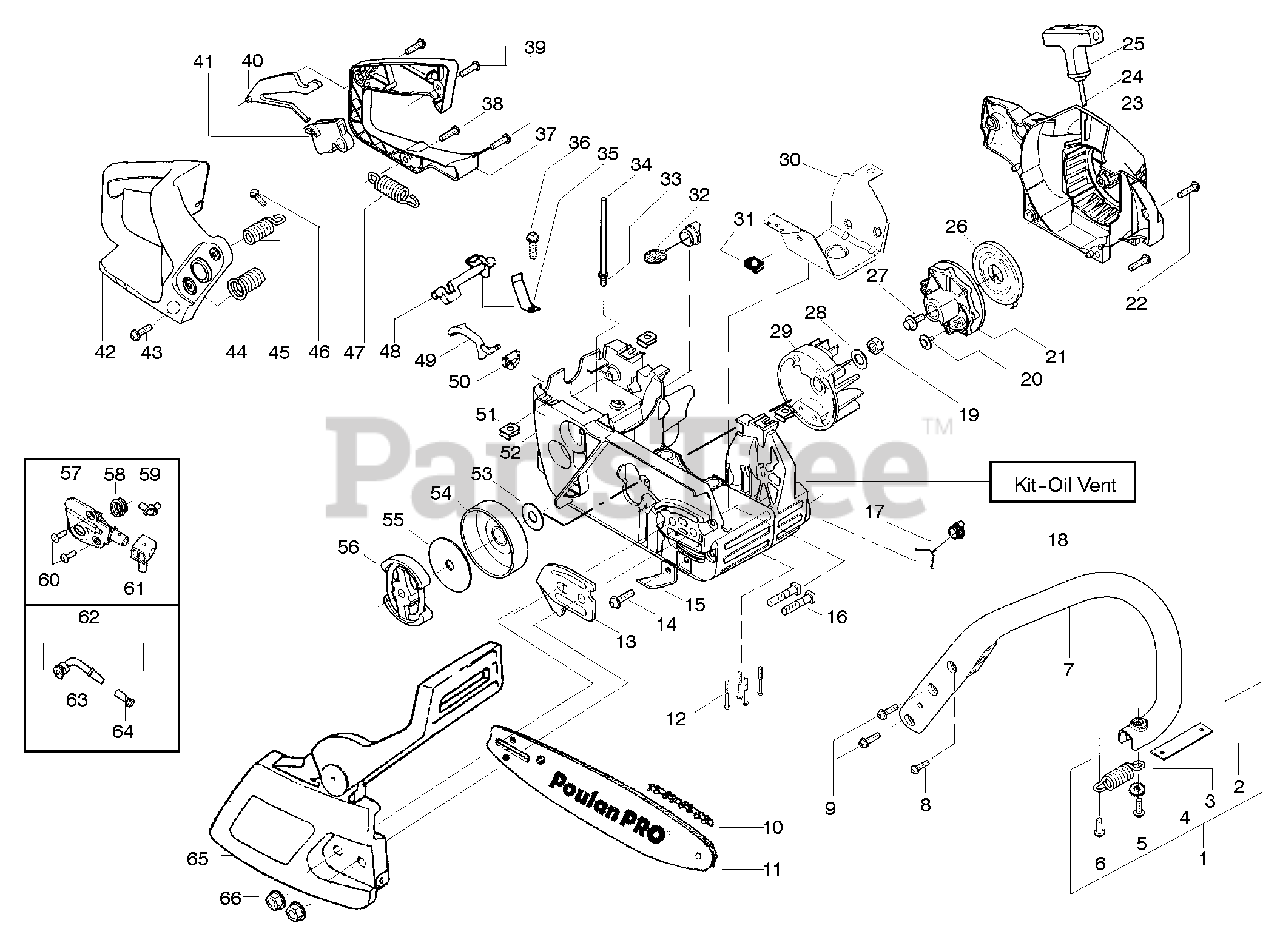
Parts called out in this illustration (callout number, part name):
1	Assy.-Isolator
2	Limiter Strap
3	Spring-Isolator
4	Washer
7	Front Handle
10	Chain -16"
11	Bar - 16"
13	Plate-Bar Mount.
15	Chain Catcher
16	Bolt-Bar
17	Assy-Oil Cap
18	Kit-Oil Vent
19	Nut-Flywheel
21	Starter Pulley
23	Housing-Fan
24	Kit - Rope
25	Handle-Starter
26	Spring-Recoil
28	Washer-Flywheel
29	Assy-Flywheel
30	Shield - Heat
31	Clip - "U"
32	Assy-Fuel Cap
33	Fitting-fuel line
34	Kit-Fuel line (large)
35	Spring-Switch
37	Cover-Rear Handle
40	Throttle Lockout
41	Trigger-Throttle
42	Handle - Rear
43	Screw
44	Assy Isolator-lower
45	Kit-Isolator (Upper)
47	Spring-Isolator
48	Lever-Switch
49	Lever-Choke
50	Grommet-Knob
51	Nut-"U"-Type
52	Assy-Chassis
53	Washer-Thrust
54	Assy.-Clutch Drum w/bearing
55	Washer-Clutch
56	Assy. Clutch
57	Kit - Oil Pump
58	Gear-Worm Spring
59	Elbow-Oil Pickup
61	Seal Block
62	Assy-Oil Pick-up
63	Pick-up Oiler
64	Filter-Oil
65	Assy.-Chain Brake
66	Nut-Bar Mounting
